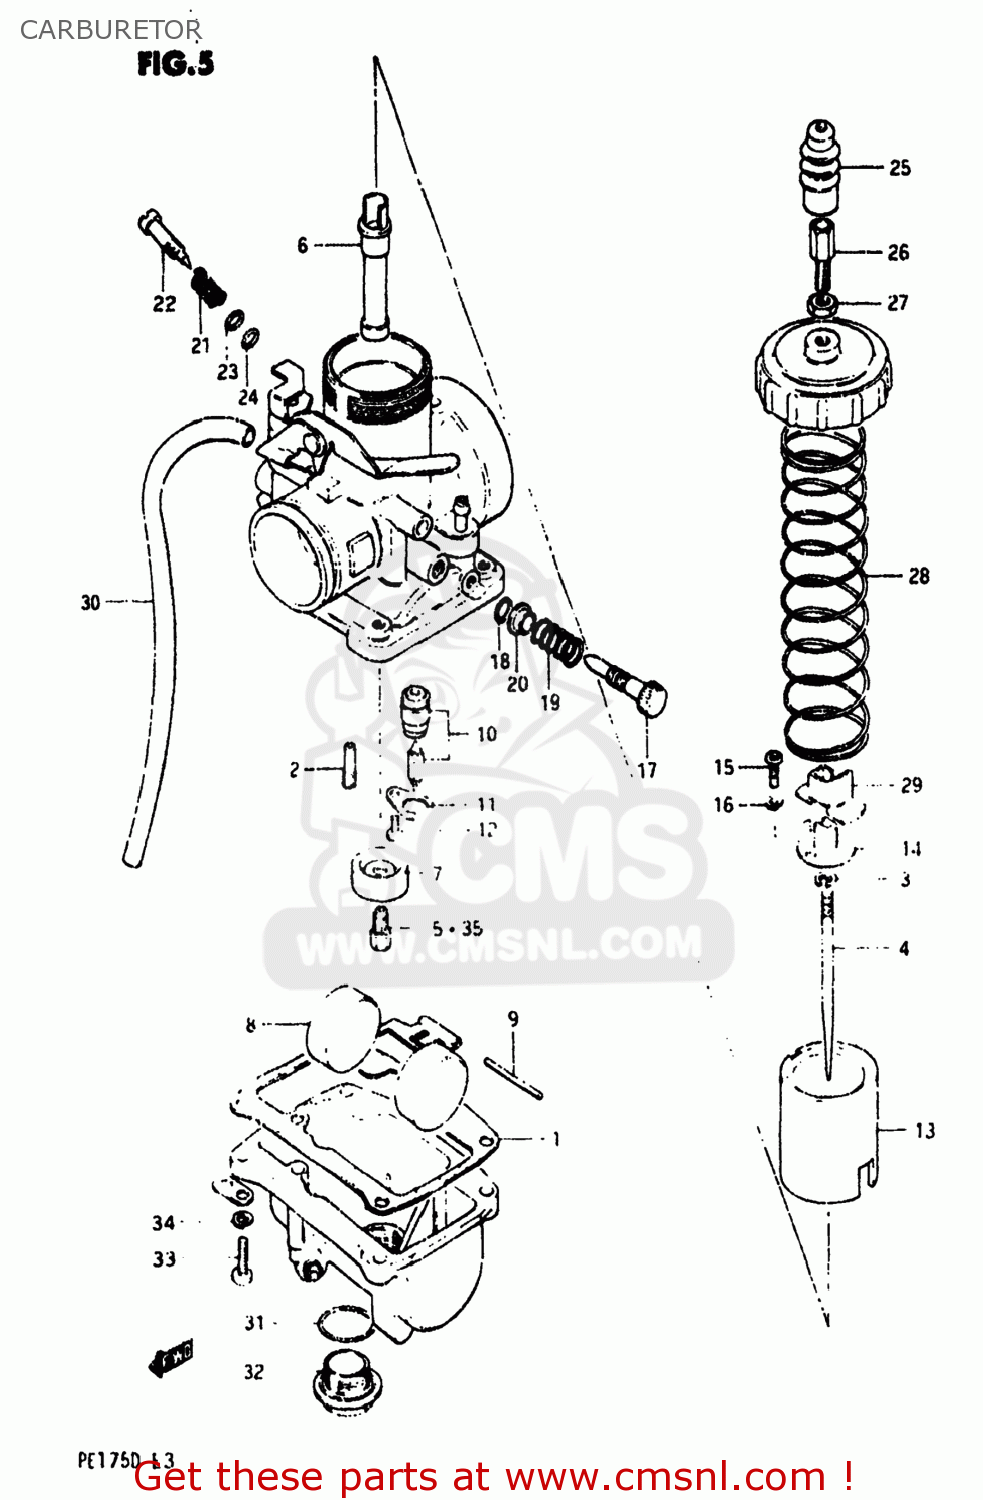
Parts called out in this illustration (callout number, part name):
1	GASKET,FLOAT CAHMBER (NAS)
2	JET
3	CLIP
4	NEEDLE,JET
5	JET
6	JET,NEEDLE
7	RING,MAIN JET FIXING
8	FLOAT
9	PIN,FLOAT
10	VALVE ASSY,NEEDLE
11	PLATE
12	SCREW
13	VALVE,THROTTLE
14	CONNECTOR
15	SCREW
16	LOCK WASHER
17	SCREW,THROTTLE STOP
18	O RING
19	SPRING,THROTTLE STOP
20	COVER
21	SPRING
22	SCREW,PILOT AIR
23	WASHER,PILOT AIR SCREW
24	O RING
25	CAP,CABLE ADJUSTER
26	ADJUSTER,CABLE
27	NUT
28	SPRING,THROTTLE VALVE RETURN
29	COVER,HOLDER
30	HOSE
31	O RING(D:1.5,ID:19.5)
32	PLUG
33	SCREW
34	LOCK WASHER
35	JET
